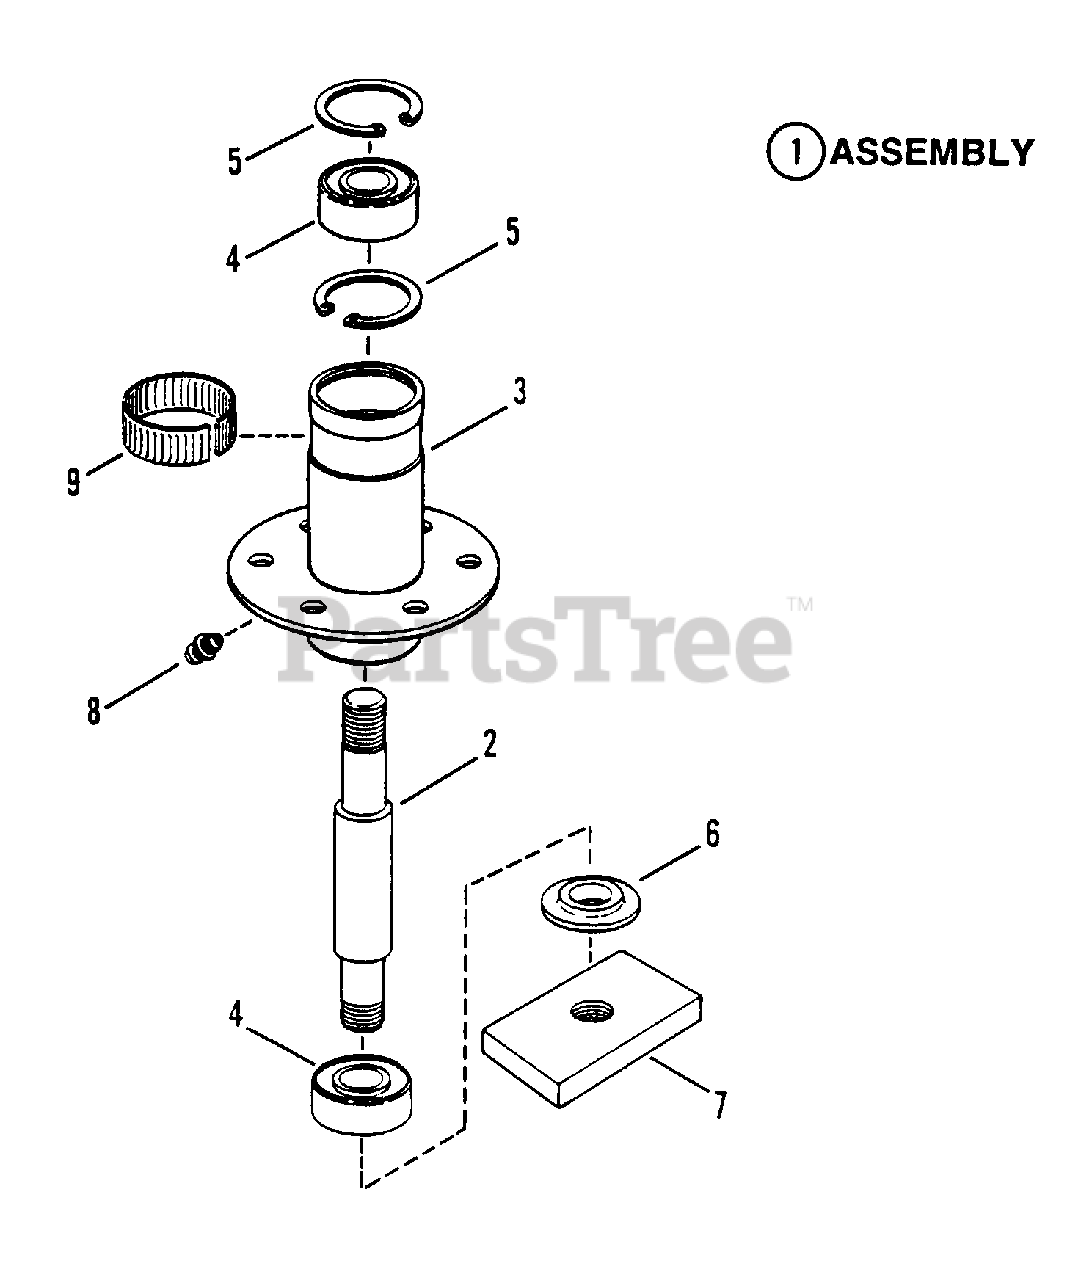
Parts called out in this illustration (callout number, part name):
1	ASSEMBLY, Spindle
2	SPINDLE
3	HOUSING, Spindle
4	BEARING, Spindle
5	RING, Retaining
6	WASHER, Spindle
7	HOLDER, Blade
8	FITTING, Lube (Press fit for .187 hole-no ball)
9	RING, Tolerance
